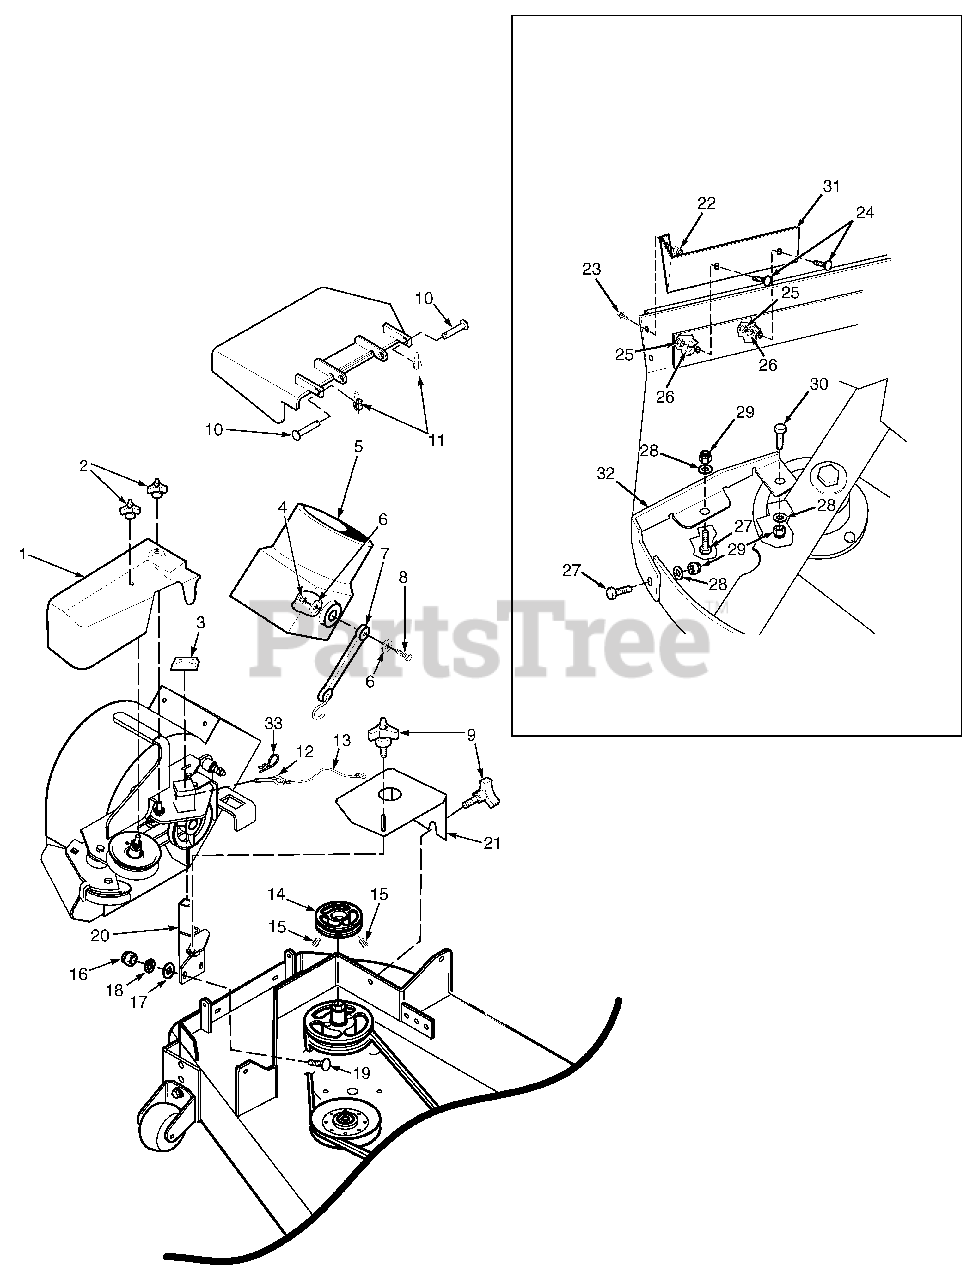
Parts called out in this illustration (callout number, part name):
1	Belt Cover, GC-STT - 52"
1	Belt Cover, GC-STT - 61"
2	Wingnut, Plastic 3/8" Small
3	Cap, Square Vinyl
4	Nut, Elastic Stop 1/4-20
5	Adapter w/Strap
6	Flatwasher, 1/4-.312 x .750 x .065
7	Rubber Strap 7-3/4"
8	Bolt, Hex Head 1/4-20 x 1-1/4"
9	Knob W/Stud, 3/8-16 x 1-1/4"
10	Clevis Pin, 5/16 x 1-1/2"
11	Pin, Rue Cotter 5/16 Dia.
12	Pin, Ring 1/2 x 2-1/4"
13	Lanyard
14	Pulley, 4-1/2" for 52" Deck
14	Pulley, 5-1/2" for 61" Deck
15	Setscrew, 5/16-18 x 3/8"
16	Nut, Elastic Stop 1/2-13
17	Flatwasher, 1/2-.531 x 1.062 x .095
18	Lockwasher, 1/2"
19	Bolt, Hex Head 1/2-13 x 1-1/2"
20	Mounting Post Weldment, Blower - 52"
20	Mounting Post Weldment, Blower - 61"
21	Belt Cover, - 52"
21	Belt Cover Assembly, - 61" w/Cap
22	Nut, Serrated Flange 1/4-20
23	Bolt, Hex Head 1/4-20 x 3/4"
24	Bolt, Carriage 3/8-16 x 1"
25	Nut, Elastic Stop 3/8-16
26	Flatwasher, 3/8-.391 x .938 x .105
27	Bolt, Hex Head 5/16-18 x 1"
28	Flatwasher, 5/16-.375 x .875 x .083
29	Nut, Elastic Stop 5/16-18
30	Bolt, Hex Head 5/16-18 x 1-3/4"
31	Baffle, 52"
31	Baffle, 61"
31	Baffle, 72"
32	Baffle, 52" Deck
32	Baffle, 61" Deck
32	Baffle, 72" Deck
33	Hair Pin Cotter, .177 x 3-1/4"
